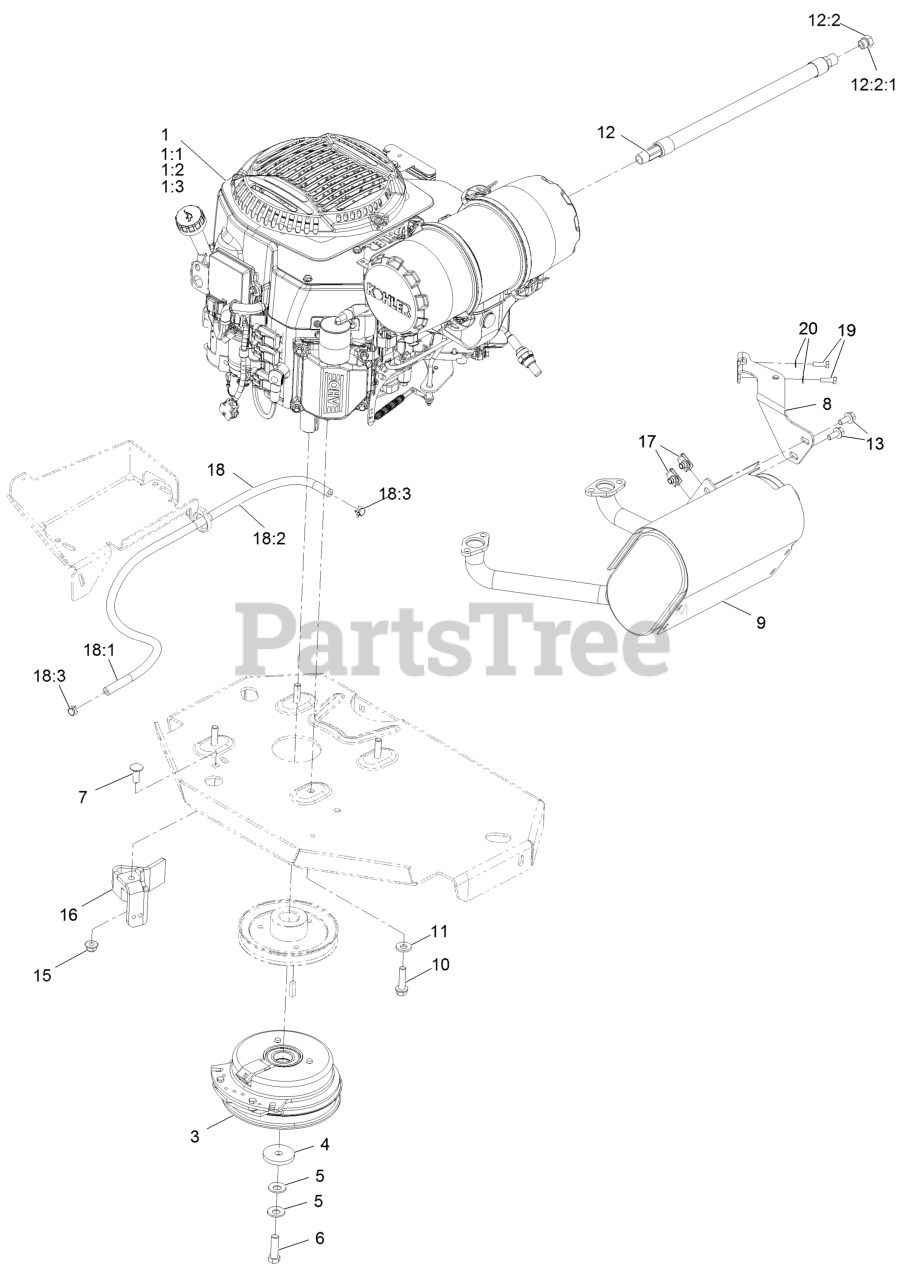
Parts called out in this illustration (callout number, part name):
3	Clutch Kit
4	Washer-Clutch
5	Washer-Spring
6	Screw-HH
7	Screw-CARR
8	Muffler Bracket Kit
9	Kit, Muffler-Koh Ecv
10	Screw-HWH
11	Washer-Belleville
12	Oil Drain Hose ASM
12:2	Plug-HH
12:2:1	O-Ring
13	Screw-HHF
15	Nut-Flange, NI
16	Clutch-Anchor
18	Fuel Line ASM
18:1	Hose-Fuel
18:2	Sleeve-Thermal
18:3	Clamp-Hose
19	Screw-HH
20	Washer-Spring
